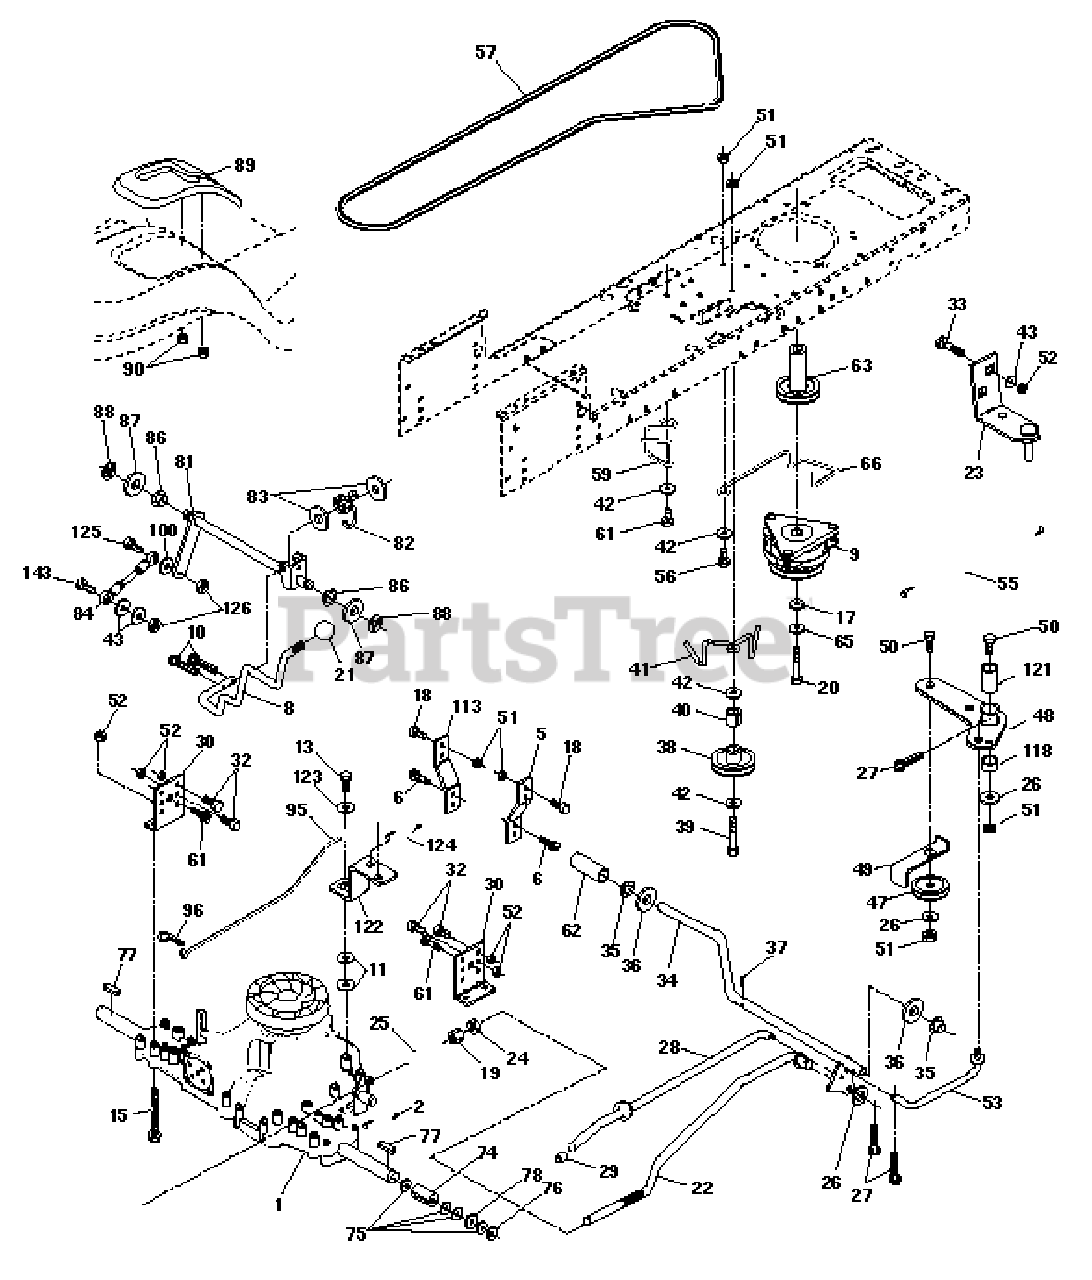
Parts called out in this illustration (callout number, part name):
2	Spring, Return Brake
5	Strap Torque
6	Screw Thdrol 5/16-18 x 3/4
8	Rod Shift Hydro LT
9	Clutch Elect
10	Pin Cotter 1/8 x 1 CAD
11	Washer Plate Shf
13	Bolt 1/4-28 Unf Gr. 8 W/Patch
15	Bolt Hex Flghd 5/16-18 Gr. 5
17	Washer 1-1/2OD x 15/32 ID x .250
18	Bolt Fin Hex 3/8-16 Unc x 1 Gr. 5
19	Nut Lock Hex W/Wsh 3/8-16 Unc
20	Bolt Hex 7/16-20 x 4-1/4 5 Ga. 1.38
22	Rod, Brake
23	Bracket Asm Mtg. Cl
24	Nut, Hex Jam 3/8-16 Unc
25	Spring, Brake Rod
26	Washer
27	Pin Cotter 1/8 x 3/4 CAD.
28	Rod, Parking Brake
29	Cap, Parking Brake
30	Bracket, Transaxle
32	Bolt Hex Hd 5/16-18 Unc x 3/4
33	Bolt RdHd Sqnk 5/16-18 Unc x 3/4
34	Shaft, Foot Pedal
35	Bearing, Nylon
37	Pin, Roll
38	Pulley, Idler, Flat
40	Spacer, Split
41	Keeper, Belt, Idler
42	Washer 13/32 x 13/16 x 12 Gauge
43	Washer 11/32 x 5/8 x 12 Ga.
47	Pulley, Idler, V-Groove
48	Bellcrank Assembly
49	Retainer, Belt
50	Bolt
51	Nut Crownlock 3/8-16 UNC
52	Nut, Crownlock 5/16-18 Unc
53	Link, Clutch
55	Spring, Return, Clutch
56	Bolt Hex 3/8-16 x 1-1/4
57	V-Belt, Ground Drive
59	Keeper, Center Span
61	Screw Thdrol. 3/8-16 x 3/4 Ty. TT
62	Cover, Pedal
63	Pulley, Engine
65	Washer
66	Keeper Belt Engine
74	Spacer, Axle PVST
75	Washer 25/32 x 1-1/4 x 16 Gauge
77	Key, Square
78	Washer 25/32 x 1-5/8 x 16 Gauge
81	Shaft Asm. Cross Hydro
82	Spring Torsion T/A
83	Washer 17/32 x 3/4 x 16 Ga.
84	Rod, Tie PVST 20"
86	Bushing Rod Strig. 629/632 ID
87	Washer 21/32 x 1-1/4 x 16 Ga.
88	Ring Klip #5304-62
89	Console, Shift
90	Nut Self-Thd Wsh-Hd 1/4 Zinc
95	Rod Asm Bypass PVST
96	Retainer Spring 1" Zinc/Cad
100	Washer 11/32 x 3/4 x 16 Ga.
113	Strap Torque LH LT
118	Spacer Bellcrank
121	Nyliner Clutching STL
122	Plate Bypass PVST
123	Washer 9/32 x 5/8 x 16 Ga.
124	Spring Return PVST
125	Bolt Fin Hex 5/16-18 Unc x 1
126	Nut Lock 5/16-18 Unc
143	Bolt Fin Hex 5/16-18 Unc x 1-1/4
